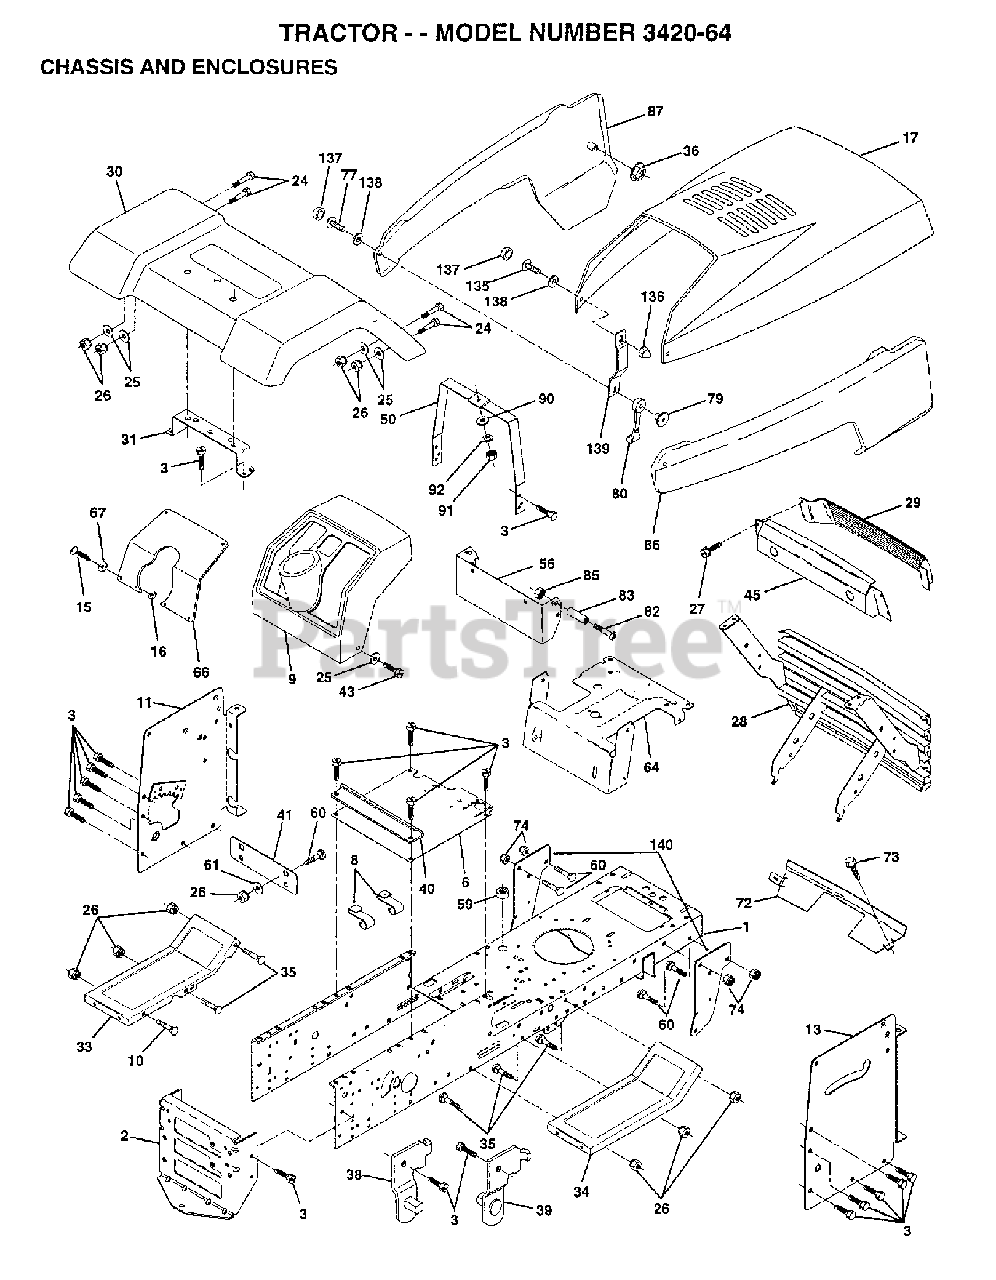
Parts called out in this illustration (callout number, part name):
1	CHASSIS WLD MT 11G
8	CLIP,INSULATOR
17	Poulan TBD
25	WASHER
26	NUT
30	Poulan TBD
31	BRACKET.SUPPORT.FENDER
33	Poulan TBD
34	Poulan TBD
36	PAL NUT LT
38	BRACKET LH PIVOT
39	BRACKET RH PIVOT
41	Plate
43	SCREW GTV
50	DASH SUPT YP
64	DASH LOWER LT
66	Poulan TBD
67	WASHER
72	Poulan TBD
73	SCREW CRT
74	LOCKNUT
77	SCREW
79	NUT.WELD
80	LATCH.HOOD.
82	SCREW
83	SPACER LT
85	NUT **
86	Poulan TBD
87	Poulan TBD
90	WASHER PM
91	NUT
92	LOCKWASHER
135	SCREW 10-24X3/8
136	NUT
137	SNAP CAP LT
138	WASHER LT
139	BRACKET.SUPPORT.HOOD/PANEL.NLA
